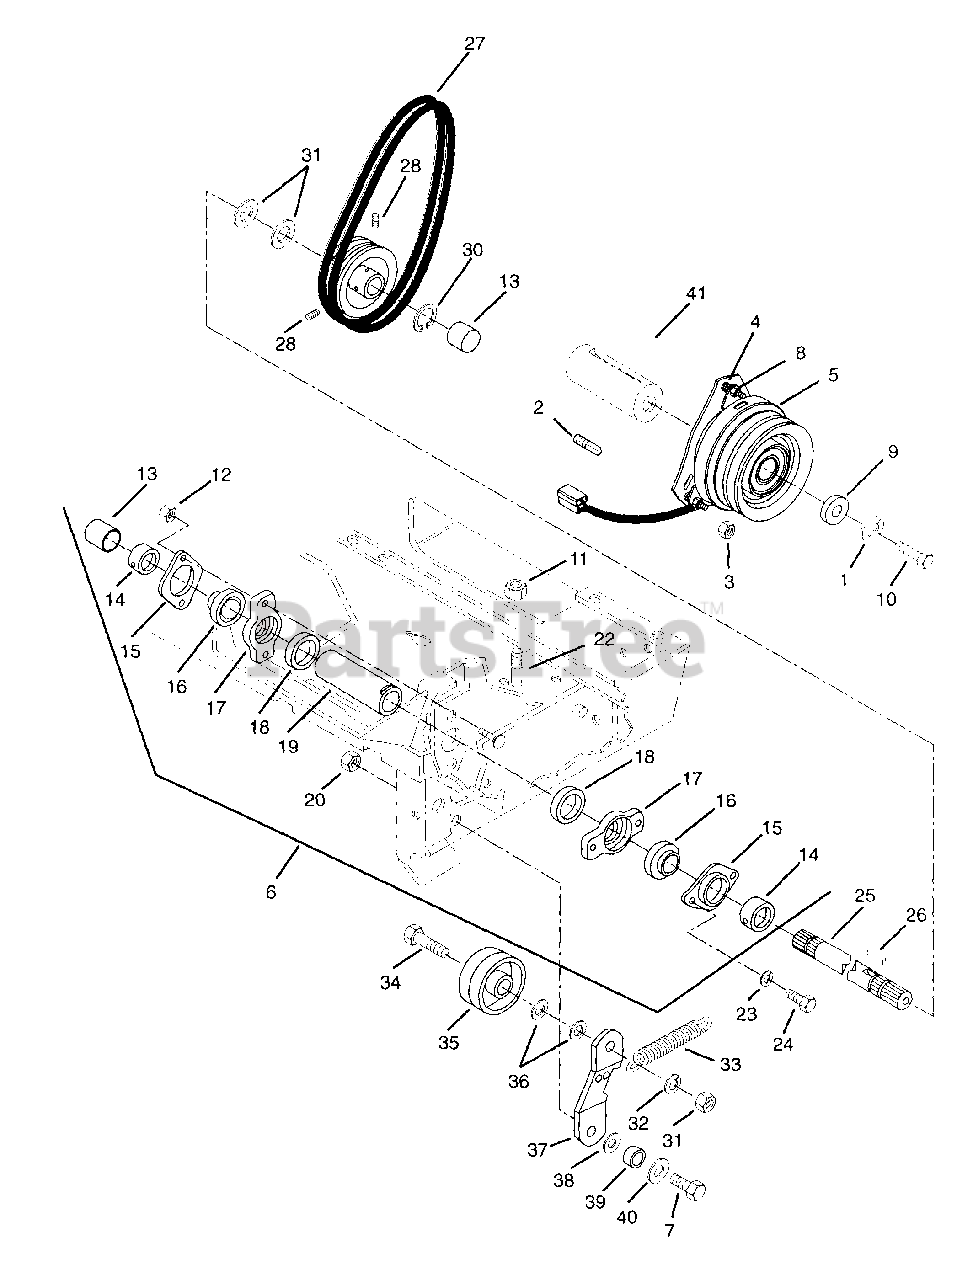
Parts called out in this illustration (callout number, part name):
1	WSHR-LK .438X.133 HVY
2	STUD - CLUTCH
3	NUT-LK-CTR .375-16 GR A PL
4	SG-COMP WARNER ELEC.
5	CLUTCH-ELEC. WARNER I-5215-62B
6	FRONT PTO KIT
7	BLT-HEX .50-13X1.25 PL GR2
8	NUT-LK WARNER
9	WSHR-FL-STL .515X1.625X.250
10	BLT-HEX .44-20X1.50 PL GR5
11	NUT-LK-JAM-CTR .375-16 PL
12	NUT-LK-CTR .375-16 GR A PL
13	SHAFT COVER
14	BEARING COLLAR
16	BRG/W COLLAR 1.0 X 2.047 X.844
17	BRG FLANGE
18	BSHG-SLV 1.500X1.750X.560
19	PTO TUBE
20	NUT-LK-CTR .50-13
21	BLT-RDHDSQNK .38-16X1.50 PL
22	LOCK STUD
23	WSHR-LK .375X.094 MED PL
24	BLT-HEX .38-16X1.50 PL GR2
25	FRONT PTO SHAFT
26	KEY-FTHR .25X1.25X.25 SAE
27	V-BELT, 4L-WRAPPED (SET)
28	SCR-SET .32-18X.38 SKHCUPNL OH
29	To Pulley at bottom of Belt
30	RG-RTNG-EXT 1.00X.042
31	WSHR-FL-STL 1.010X1.505X.062PL
32	NUT-HEX .375-16
33	SPRING ASSEMBLY
34	BLT-HEX .38-16X2.00 PL GR2
35	IDLER-FLAT 3.25 X .38 NWHAMSHR
36	WSHR-FL-STL .38X.875X.083 PL
37	IDLER ARM
38	SHIM SPACER
39	SPACER .512X.747X.208
40	WSHR-FL-STL .518X2.000X.105
41	KEY-SQ .25X.625X.25 SAE 8630
